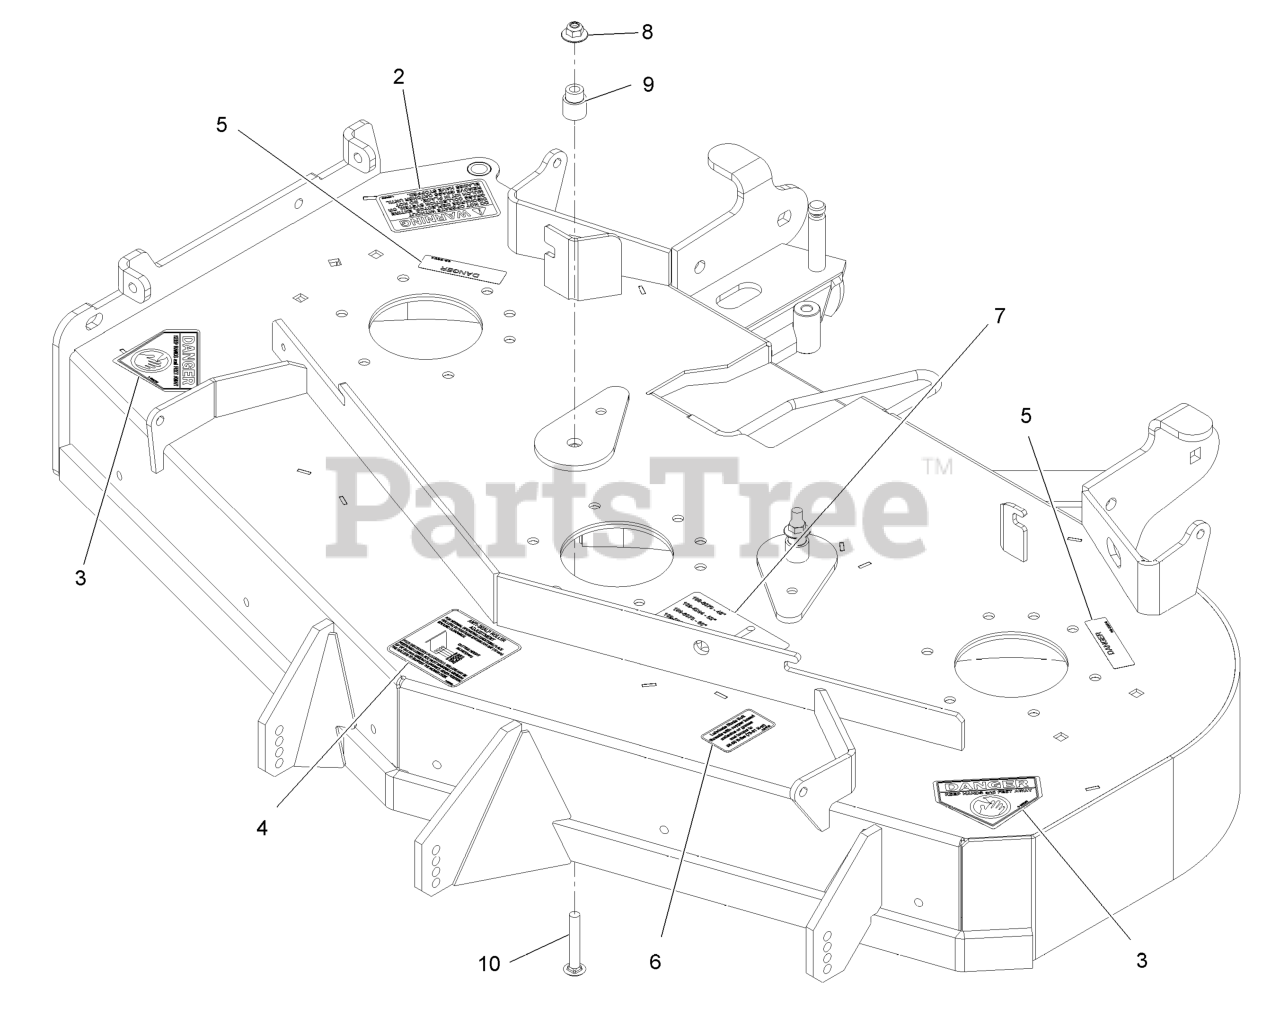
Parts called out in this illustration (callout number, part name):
2	DECAL-WARNING, DISCHARGE
3	DECAL-DANGER
4	DECAL,ANTISCALP
5	DECAL-COVER, MISSING
6	DECAL,BOLT TORQUE
7	DECAL,BELT ROUTING
8	Nut-Nyloc 3/8-16 Flg
9	BUSHING-IDLER
10	SCREW-CARR
